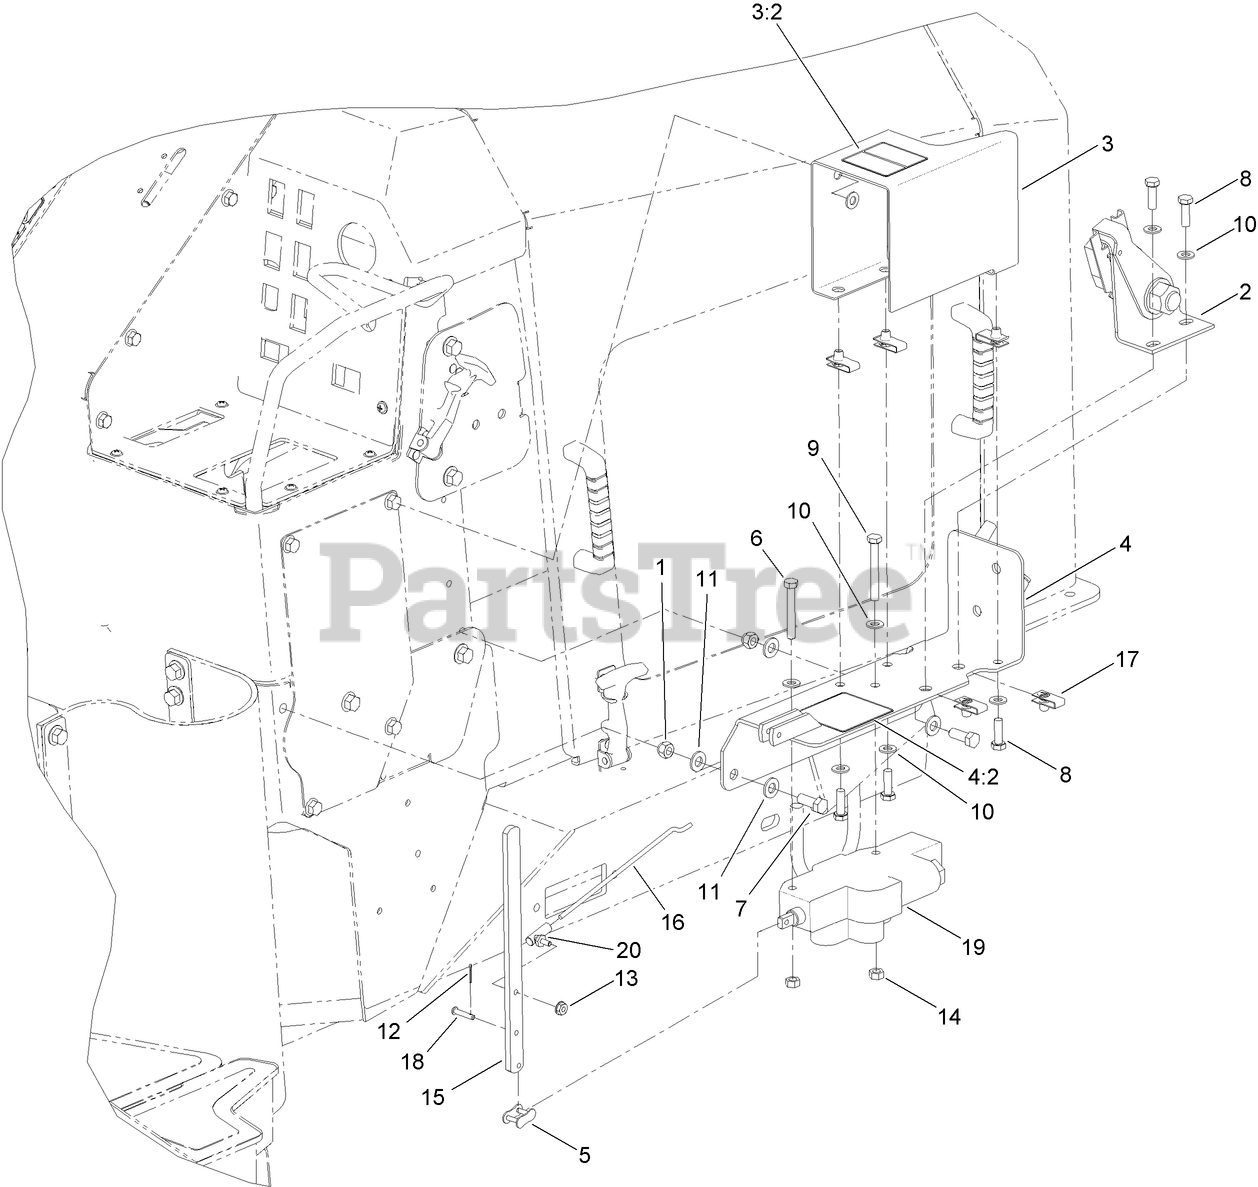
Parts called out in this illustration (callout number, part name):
1	NUT-HEX
2	NEUTRAL START SWITCH ASM
3	COVER ASM
3:2	DECAL-ATTACHMENT SELECTOR
4	BRACKET ASM
4:2	DECAL-CHAIN DIRECTION
5	LINK-#50, CONNECT (SINGLE PITCH)
6	SCREW-HH
7	SCREW-HH
8	SCREW-HH
10	WASHER-PLAIN
11	WASHER-FLAT
12	PIN-COTTER
13	NUT-KEPS
14	NUT-LOCK, CONE
15	LEVER-VALVE
16	ROD-SWITCH, NEUTRAL
17	NUT-U TYPE
18	PIN-CLEVIS
19	HYD VALVE ASM
20	JOINT-Ball
